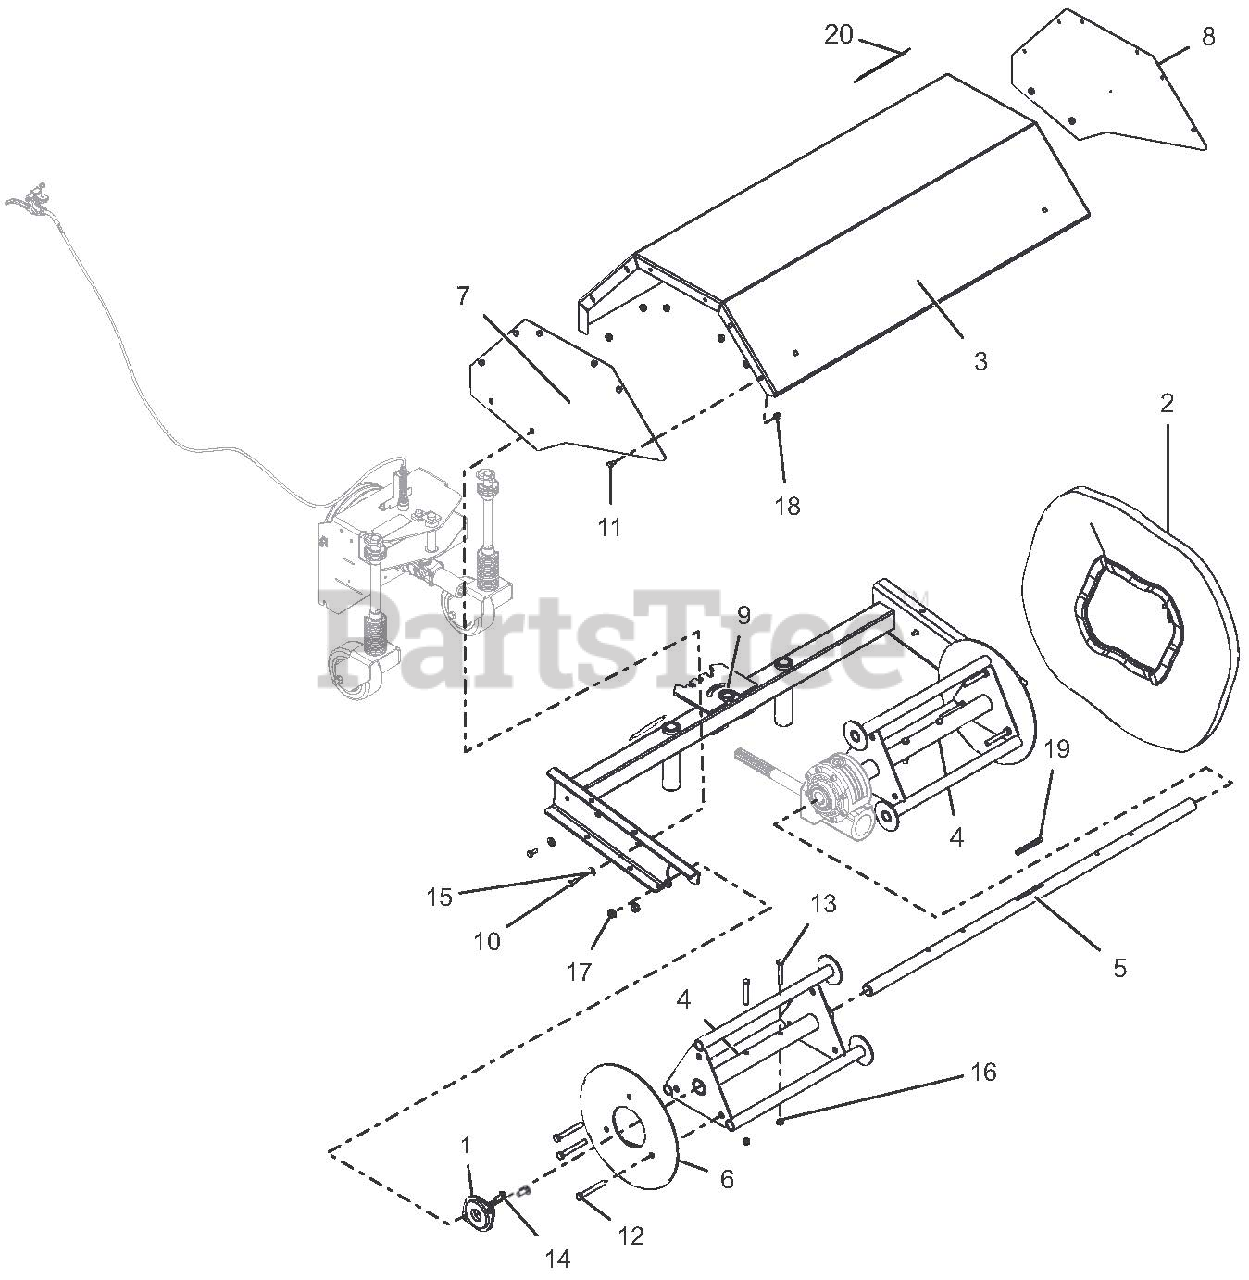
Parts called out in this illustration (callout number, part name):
1	BEARING,2 BOLT FLANGE 1-1/8 ID
2	KIT, BRISTLE - SET OF 18
3	COVER, TOP - 36" BRUSH W/DECAL
4	PB36 DRIVE CORE SERVICE KIT
5	CENTER, SHAFT
6	PLATE, END RETAINER
7	WLDT, SIDE COVER - RH
8	WLDT, SIDE COVER - LH
9	FRAME, POWER BROOM 36"
10	@BLT-HEX .25-20X.75 GR5 YWZC
11	@BLT-HEX .25-20X.50 GR5 YWZC
12	BLT-HEX .38-16X3.00 GR5 FTH YZ
13	@BLT-HEX .31-18X2.25 GR5 YWZC
14	@BLT-RDHDSQNK .38-16X1.00 G5YZ
15	@WSHR-FL-STL.312X.734X.065 YWZ
16	@NUT-LK-CTR .31-18 YWZC
17	@NUT-LK-TOP-FLG .38-16 YWZC
18	@NUT-LK-TOP-FLG .25-20 YWZC
19	KEY .25 X .25 X 3IN
20	DECAL, DANGER -POWER BRUSH-CE
